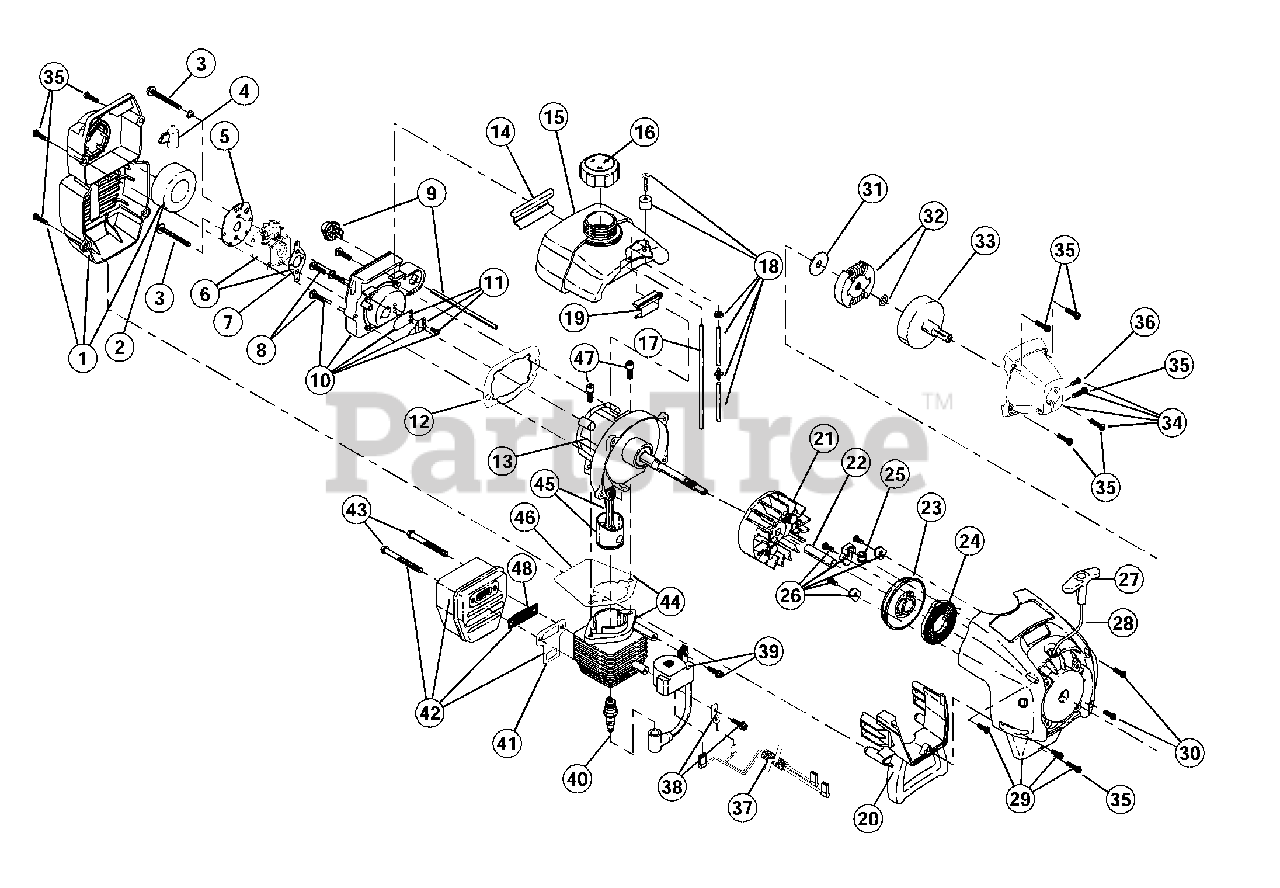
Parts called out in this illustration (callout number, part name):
1	Air Cleaner/Muffler Cover Assembly
2	Air Cleaner Filter
3	Carburetor Mounting Screws
4	Choke Extention
5	Choke Plate
6	Carburetor Assembly
7	Carburetor Gasket
8	Carb Mount Screw
9	Primer and Hose Assembly
10	Carb Mount Assembly
11	Reed Assembly
12	Carburetor Mount Gasket
13	Crank Case Service Assembly
14	Rear Mounting Pad
15	Fuel Tank Assembly
16	Fuel Cap Assembly
17	Fuel Return Line
18	Fuel Line Assembly
19	Front Mounting Pad
20	Shroud Extension and Stand
21	Flywheel Assembly
23	Recoil Pulley Assembly
24	Recoil Spring
25	Rope Guide
26	Pulley Retainer Assembly
27	Pull Handle
29	Starter Housing Assembly
30	Housing Screws
31	Clutch Washer
32	Clutch Rotor Assembly
33	Clutch Drum Assembly
34	Clutch Cover Assembly
35	Cover Screw
36	Anti-Rotation Screw
37	Wire Leads and Sleeve
38	Ground Tab
39	Module Assembly
40	Spark Plug
41	Exhaust Gasket
42	Muffler Assembly
43	Muffler Mounting Bolt Assembly
44	Cylinder Assembly
45	Piston and Rod Assembly
46	Cylinder Gasket
47	Cylinder Bolt
48	Spark Arrestor Screen
